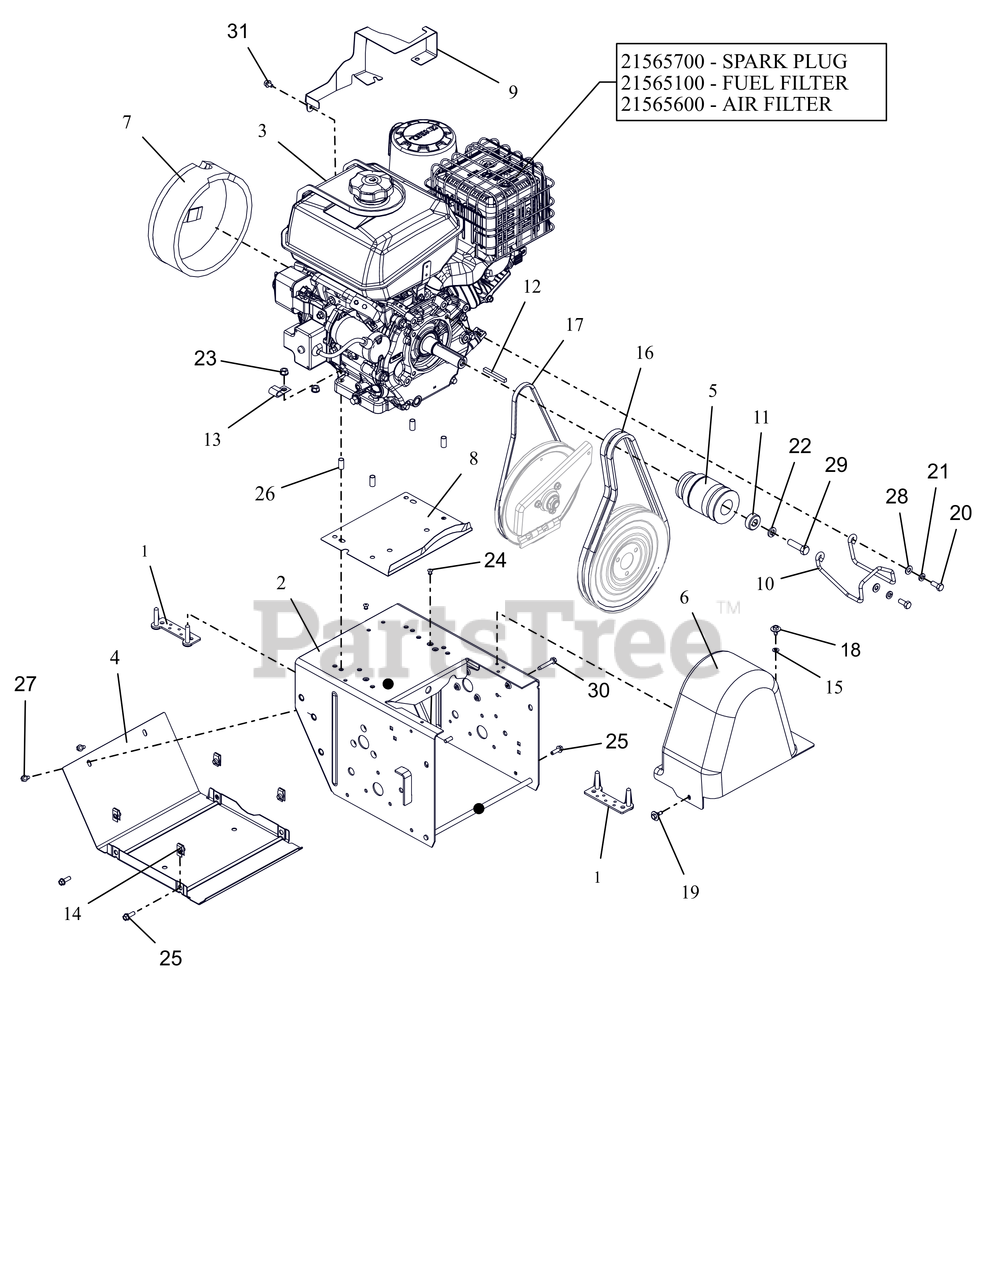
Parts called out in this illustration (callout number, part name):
1	STRAP, ENGINE BOLT-LARGE BRIGG
2	FRAME, MAIN - PRO (WELDMENT)
3	ENGINE, KOHLER - CH395 120V
3	PLUG,SPARK - KOHLER CH395/440
3	FILTER, FUEL (IN TANK)
3	FILTER,AIR - KOHLER CH395/440
4	COVER, BOTTOM
5	SHEAVE, SUBARU EX27
6	COVER, BELT-TALL PRO
7	COVER, RECOIL - KOHLER CH395
8	BAFFLE, WATER - LARGE BLOCK
9	BRKT, ENGINE - KOHLER CH395
10	FINGER, BELT
11	BSHG-SPACER .47X1.25X.50
12	KEY .25X.25X2.25
13	J-CLAMP
14	NUT-RTNR .25-20X.56
15	NUT-PUSH .25X.50 O.D.
16	V-BELT, HA-RAW EDGE (SET)
17	V-BELT, 3L-RAW EDGE
18	SCR, TAP .25-20X.50 LG HWH ZCC
19	SCR-TAP .25-20X.5 CAPTIVE
20	BLT, HEX .31-24X.750 G5 ZCC
21	WSHR, LK-HVY .312X.097 ZCC
22	WSHR, LK-REG .438X.109 ZCC
23	NUT,LK-CTR-FLG .31-18 GF ZCC
24	RVT, POP .1875 ZCC
25	BLT, HWH .25-20X.75 G5 ZCC
26	BSHG-SLV .325X.400X.795
27	SCR-TAP .25-20X.50 HWH ZCC
28	WSHR,FLT .344X.688X.065 ZCC
29	BLT, HEX .44-20X1.50 G5ZCCEP80
30	SCR,TAP .25-20X1.50 HWH TR ZCC
31	BLT, HEX M6-1.0X10 G10.9 ZCC
